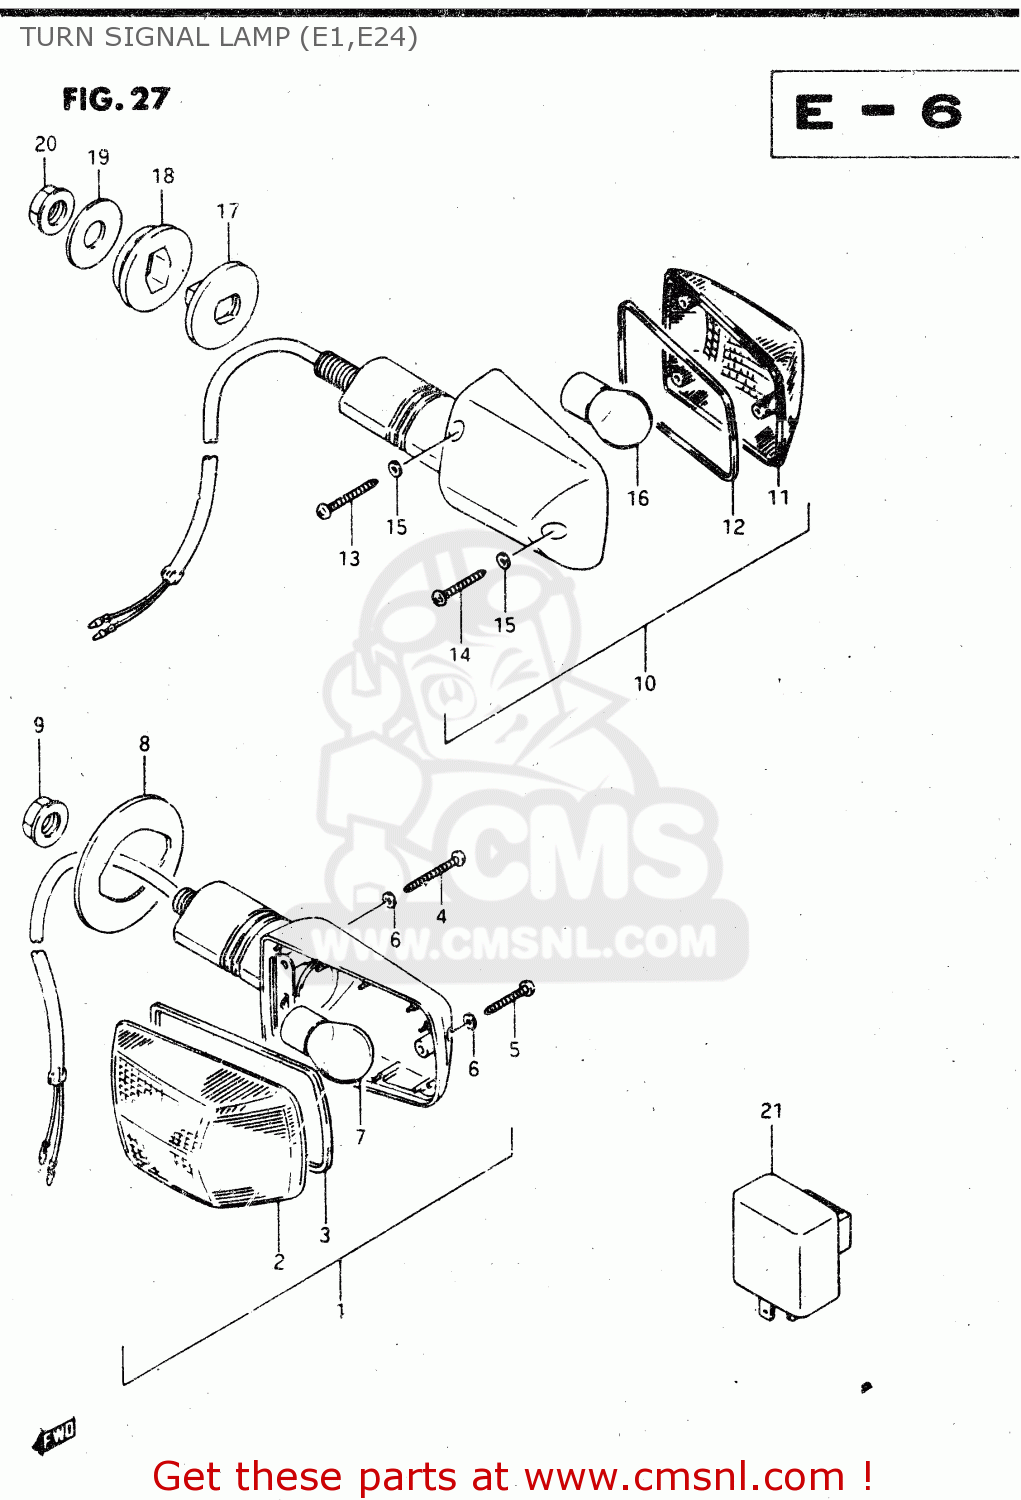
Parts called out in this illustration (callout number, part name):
1	LAMP ASSY, FRONT TURN SIGNAL
2	LENS
3	GASKET (NAS)
4	SCREW(3X30)
5	SCREW
6	GASKET (NAS)
7	BULB (12V,23W)
8	GROMMET
9	NUT
10	LAMP ASSY, READ TURN SIGNAL
11	LENS
12	GASKET (NAS)
13	SCREW(3X30)
14	SCREW
15	GASKET (NAS)
16	BULB(12V23W,STANLEY,A4577A)
17	CUSHION
18	SPACER
19	WASHER (10.2X27X1.6)
20	NUT
21	RELAY, TURN SIGNAL
